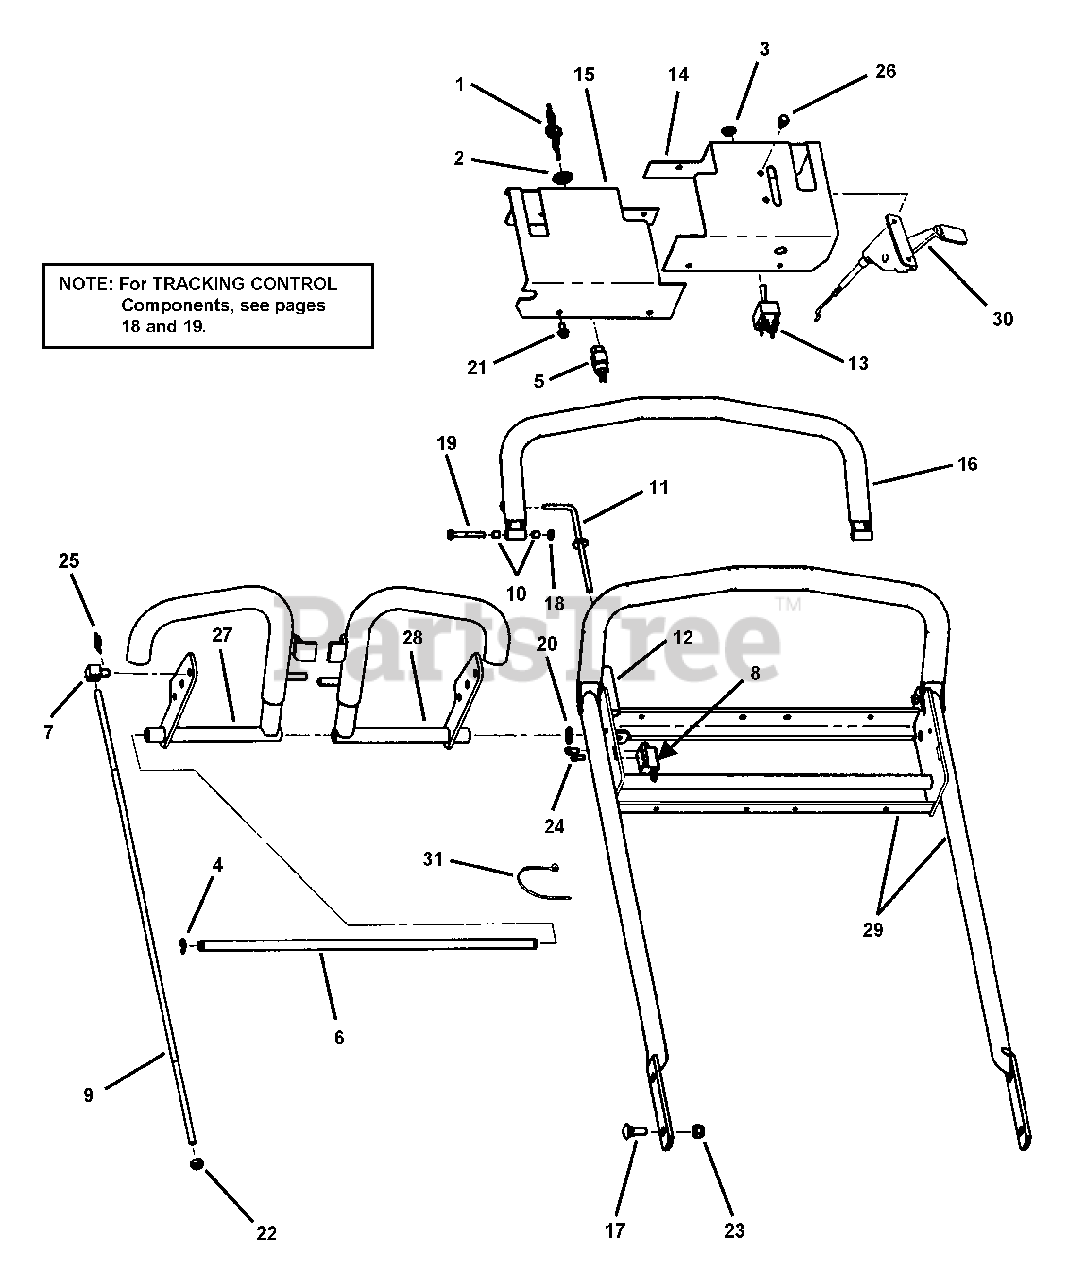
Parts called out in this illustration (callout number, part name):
1	KEY, Ignition (pair)
2	NUT, 5/8-32 Hex (Special)
3	NUT, 1/2-27 (Special)
4	E-RING, 1/2"
5	SWITCH, ON-OFF
6	ROD, Pivot
7	SWIVEL
8	SWITCH, OPC
9	ROD, Traction
10	BEARING
11	ROD, OPC
12	SPRING
13	SWITCH, Toggle
14	PANEL, Left
15	PANEL, Right
16	BAIL, OPC (Weldment)
17	BOLT, 3/8-16 x 1" Carriage, Grade 2
18	NUT, 1/4-20 Hex Jam
19	BOLT, 1/4-20 X 1-3/4" GD5 YZ
20	BUSHING, 1/2" Machine
21	SCREW, 1/4-20 x 1/2" Hex Washer Self-tap
22	NUT, 5/16-24 Grade 5
23	NUT, 3/8-16 HEX NYLON LOCK
24	SCREW, #12-14 x 1/2" Hex Washer Head, Self-tap, Grade 5
25	COTTER-PIN, 1/2" Self-Locking
26	SCREW, 1/4-20 x 3/4" Hex Washer Self-tap
27	LEVER, Traction (Right Hand) (Weldment)
28	LEVER, Traction (Left Hand) (Weldment)
29	HANDLE, Loop (Weldment)
30	CONTROL, Throttle (Briggs)
31	CABLE TIE, 7"
32	WIRE HARNESS
